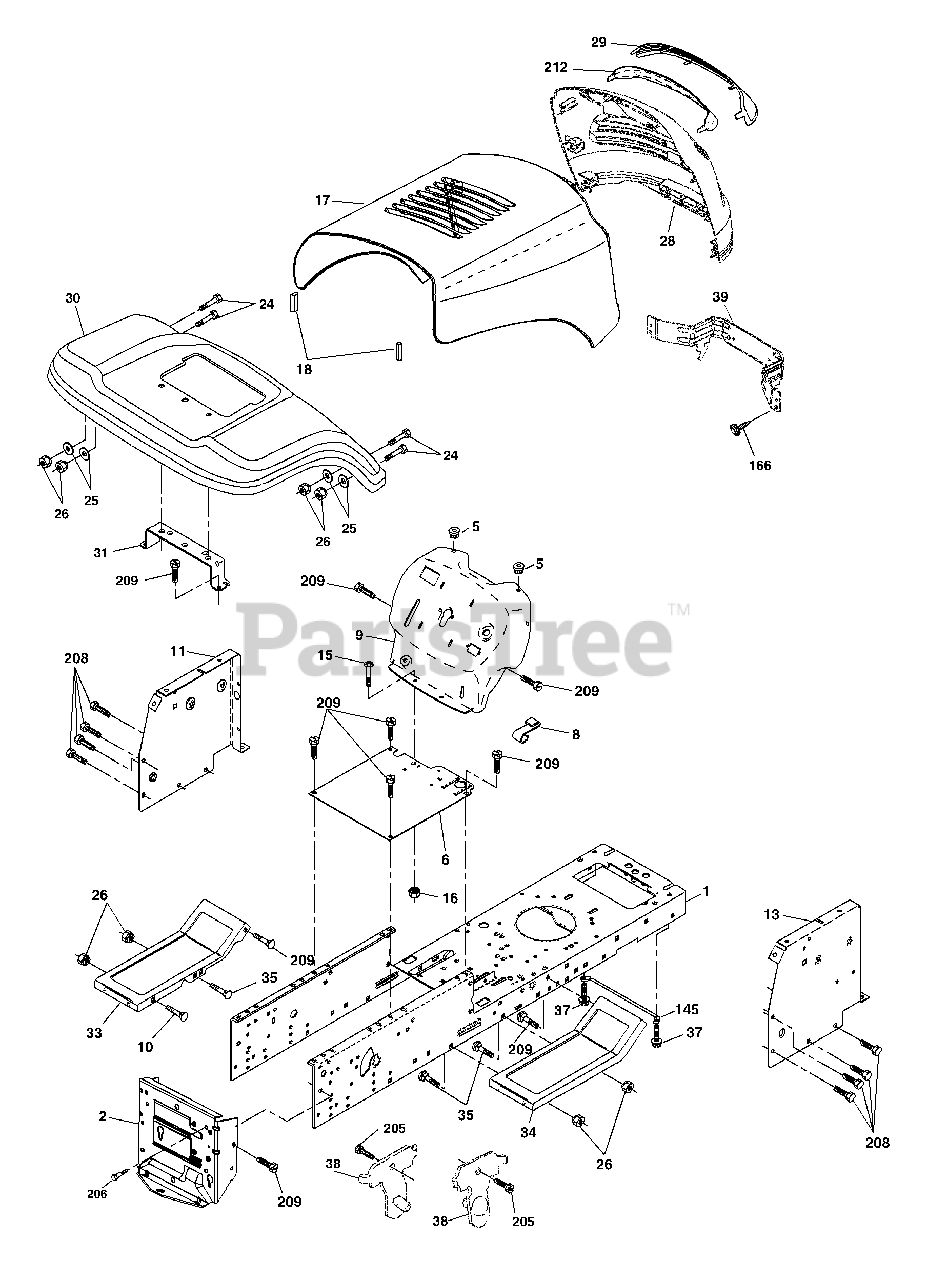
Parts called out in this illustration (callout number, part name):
1	Chassis
2	Drawbar
5	Bumper Hood/Dash
6	Saddle Slkscr Flt LT
8	Clip Retainer Slide-On
9	Dash
10	Bolt Rdhd Sqnk 3/8-16 unc x 1
11	Panel Dash LH
13	Panel Slkscr Dash RH
15	Screw Mach TRHD 5/16-18 unc x 3/4
16	Nut Keps 5/16-18 Unc
17	Hood Asm
18	Bumper Hood
24	Bolt Fin Hex 3/8-16 unc x 1 Gr. 5
25	Washer 13/32 X 13/16 x 12 Ga.
26	Nut Hex Lock W/Ins. 3/8-16 unc
28	Grille/Lens Asm
29	Lens Headlight Bar
31	Bracket Fender Repl 109873X
33	Footrest Pnt Lh
34	Footrest Pnt Rh
35	Bolt Rdhd Sht Sqnk 3/8-16 x 3/4
37	Screw Thdrol 5/16-18 x 1/2
38	Bracket Asm Pivot Mower Rear
39	Bracket Pivot ALPHA LT
145	Rod Pivot Chassis/Hood
166	Screw HWHD Hi-Lo # 13-16 x 5/8
205	Screw Thdrol 3/8-16 x 1/2
206	Bolt Shoulder 5/16-18
208	Screw thdrol 3/8-16 x 1/2
209	Screw Hex Wsh Thdrol 3/8-16
212	Insert Lens Reflective
